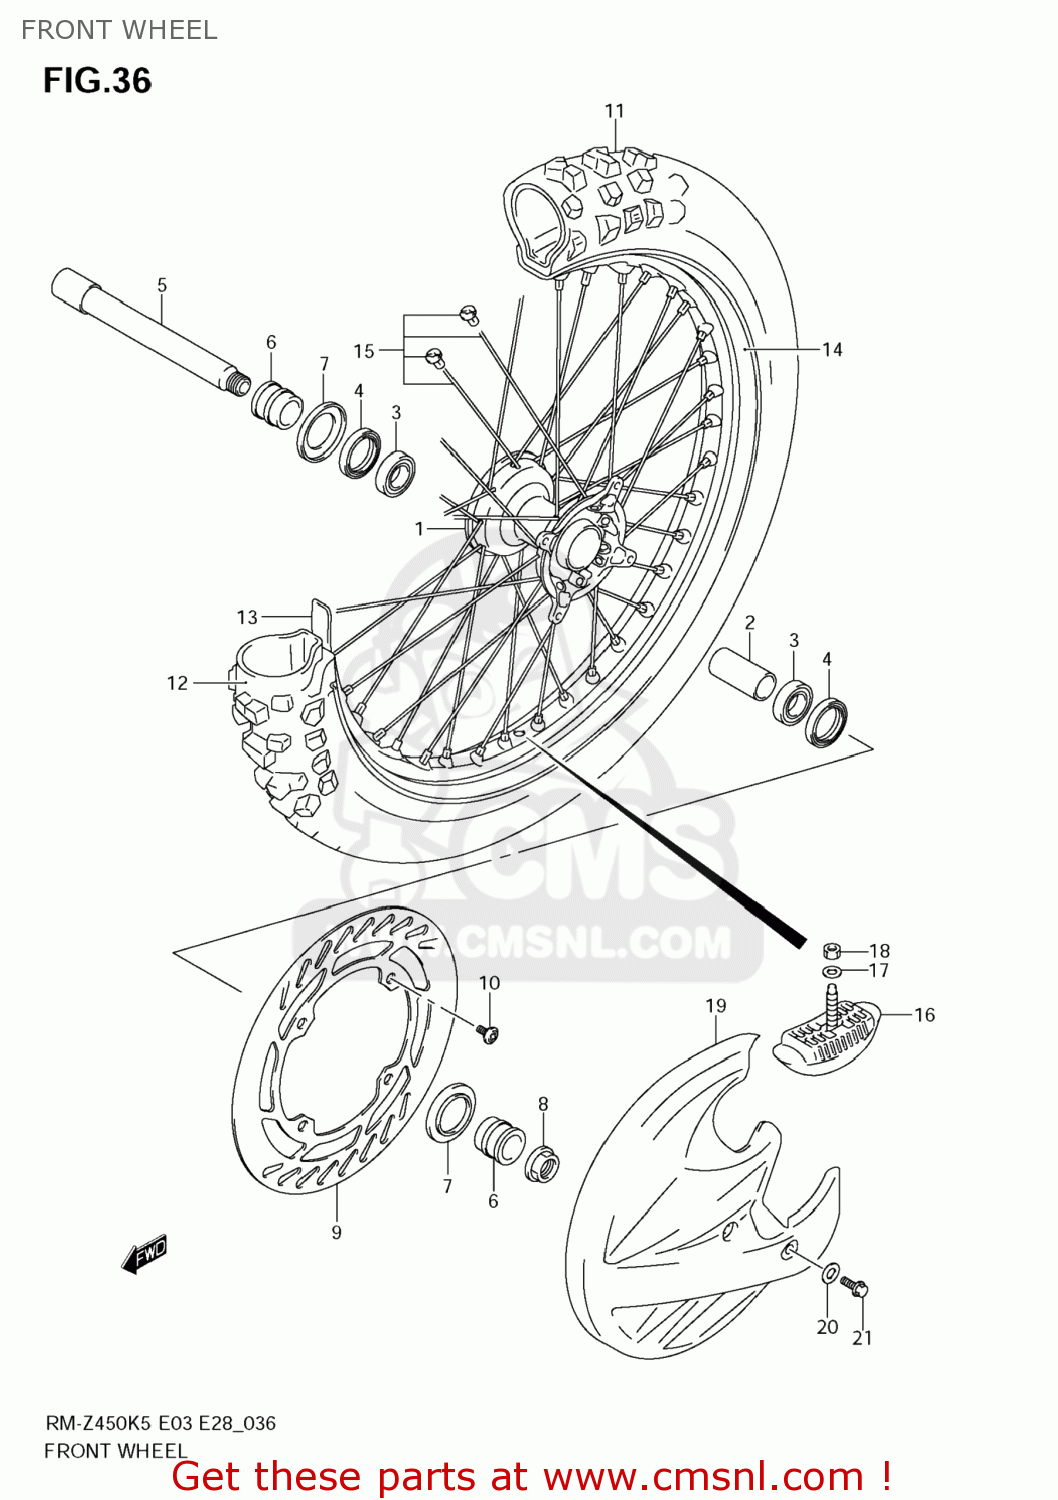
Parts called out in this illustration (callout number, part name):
1	HUB,FRONT
2	SPACER,FR HUB BEARING
3	BEARING(22X39X9)
4	SEAL,OIL(30X40X7)
5	AXLE,FR
6	SPACER,FR AXLE
7	COVER,FR AXLE SPACER
8	NUT
9	DISC,FR BRAKE
10	SCREW(6X13.5)
11	TIRE COMP,FR(9
12	TUBE ASSY,WHEEL INNER
13	PROTECTOR,WHEE
14	RIM,FR WHEEL(21X1.60 AL)
15	SPOKE SET,FR WHEEL
16	STOPPER,BEAD
17	WASHER
18	NUT
19	COVER,FR BRAKE DISC
20	WASHER,FR BRAKE DISC COVER
21	BOLT(6X12)
